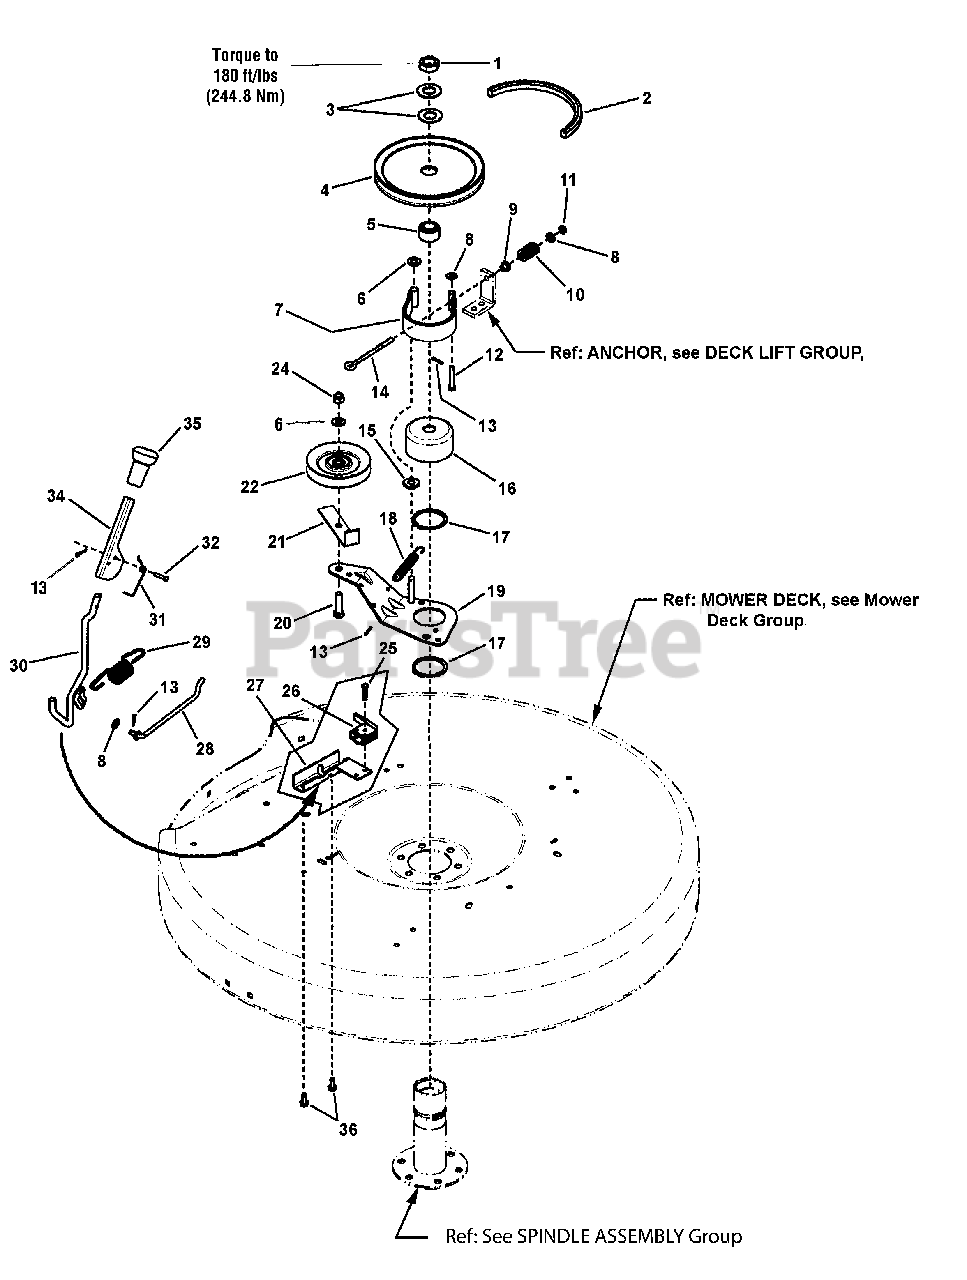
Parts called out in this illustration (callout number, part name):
1	NUT, 3/4-16 Hex Jam, GR 8
2	BELT, Spindle Drive (72.75 AA Section, Kevlar)
3	WASHER, 49/64x1-1/2x.06, Flat
4	PULLEY, Deck Spindle, 6.95 OD
5	HUB, Pulley, PM
6	WASHER, .406
7	KIT, Brake Band, 10.1" L, 1.25" H (Formed)
8	WASHER, Flat, 1/4
9	BUSHING, Flanged, .27 ID, Nylon, Black
10	SPRING, Rectangular Wire Die, Blue
11	NUT, 1/4-20 Hex Top Lock, Zinc/Clear
12	PIN, 1/4 x 1-5/8 Clevis
13	PIN, 3/32 X 3/4, GR5, Cotter, Zinc/Clear
14	EYE-BOLT, 1/4-20 x 4"
15	SPACER, .31 I.D. x .39 O.D. x 1 Nylon
16	DRUM, Brake Spindle (3 OD, 1.6 Tall)
17	RING, 2 External Retaining
18	SPRING, Extension, 4 x 1/2 Diameter
19	WELDMENT, Idler Arm, RER
20	SCREW, 3/8-16 X 1.50, Hex HD Cap, GR5, Zinc/Clear
21	RESTRICTOR, Belt, 2.18 w/Lock
22	PULLEY, Idler, .375 ID, 4 OD
24	NUT, 3/8-16, Nylock, GR5, Zinc/Clear
25	SCREW, #10F X1, GR2, Hex Washer Self-Tap, ZP
26	SWITCH, Deck Interlock (NO)
27	MOUNT, Handle/Switch
28	ROD, Idler Control
29	SPRING, Blade Handle
30	WELDMENT, Blade Engagement Handle
31	SPRING, Torsion, Flip Handle
32	PIN, 3/16 x 1" Clevis
34	HANDLE, Blade Engagement (Flip)
35	GRIP, Handle
36	SCREW, Hex Washer Head, 1/4-20 x 5/8
